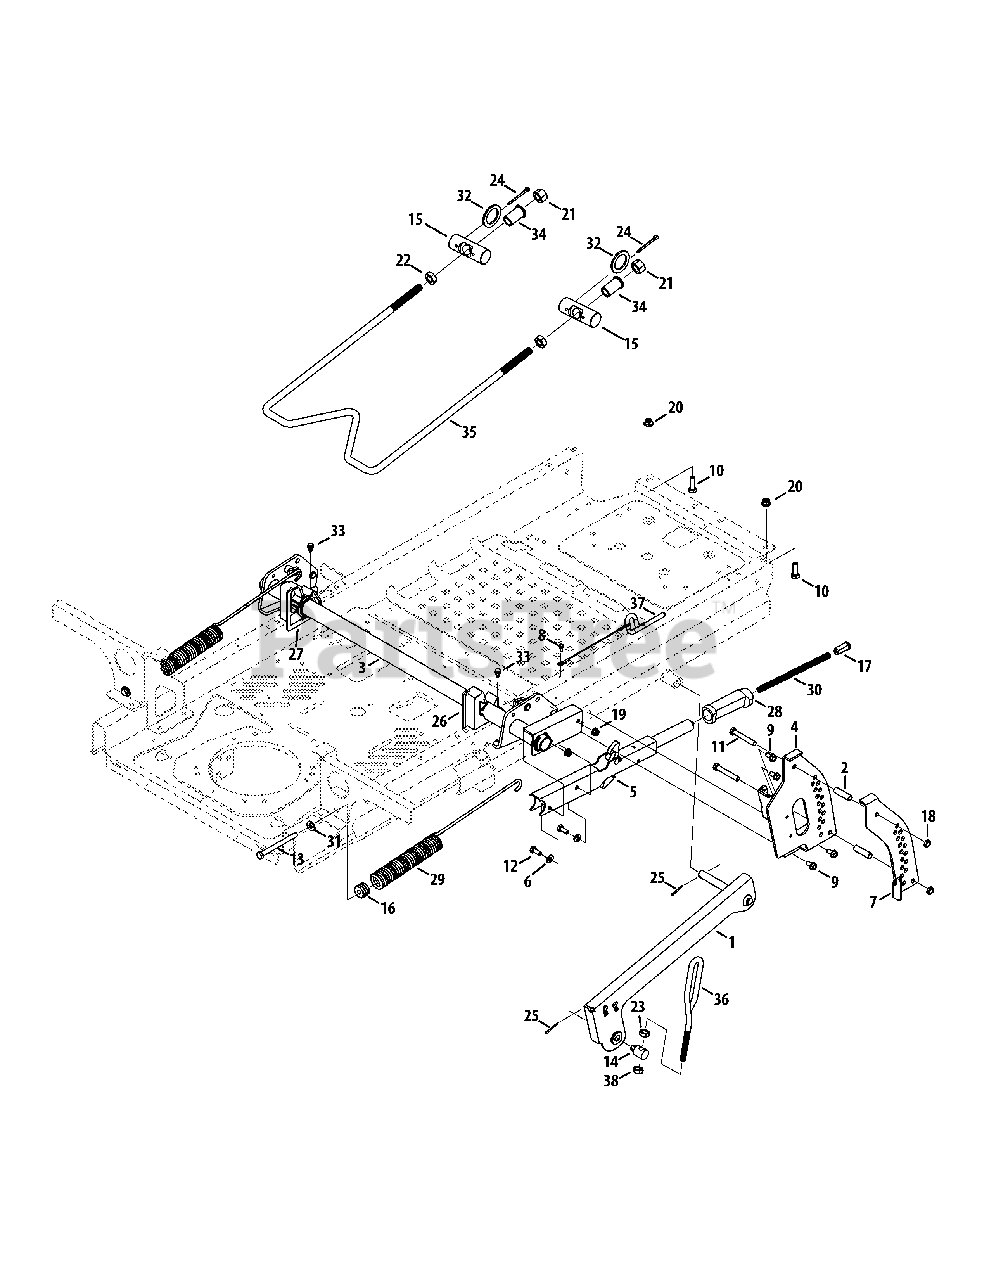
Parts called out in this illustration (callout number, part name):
2	Spacer, .386 x .63 x 1.75
3	Deck Lift Shift Assembly
4	Index Bracket Assembly
5	Latch Handle Assembly
6	Flat Washer .330 ID x .630 OD
7	Outer Index Bracket
8	Screw, #10-16, .50
9	Hex Washer Screw, 5/16-18 x .750
10	Hex Screw, 3/8-16 x 1.00
11	Hex Head Screw, 3/8-16 x 2.50
12	Hex Cap Screw, 5/16-18 x .75
13	Hex Screw, 3/8-16 x 4.25
14	Ferrule, .496 x .528
15	Pivot Pin, 1.25
16	Spring Insert
17	Handle Button
18	Jam Lock Nut, 3/8-16
19	Flange Lock Nut, 5/16-18
20	Flange Lock Nut, 3/8-16
21	Nylock Nut, 5/8-11
22	Jam Nut, 5/8-11
23	Nut, Jam, 1/2-13
24	Cotter Pin, 3/16 x 2.0
25	Cotter Pin 1/8 x 1.25
26	Deck Lift Bracket
27	Deck Lift Bracket, LH
28	Grip, Deck Lift Handle
29	Extension Spring, 1.485 OD x 17.58
30	Spring, Compression, .4 x 8.52
31	Flat Washer, .385 x .870 x .092
32	Flat Washer, 1.875 x 1.38 x .097
33	Shoulder Screw, .500 x 1/4-20
34	Flange Bearing, .875 x .702 x 1.10
35	Deck hanger Rod, 5/8
36	Lift Adjust Link
37	Lock Rod, .375
38	Hex Nut, 1/2-13
